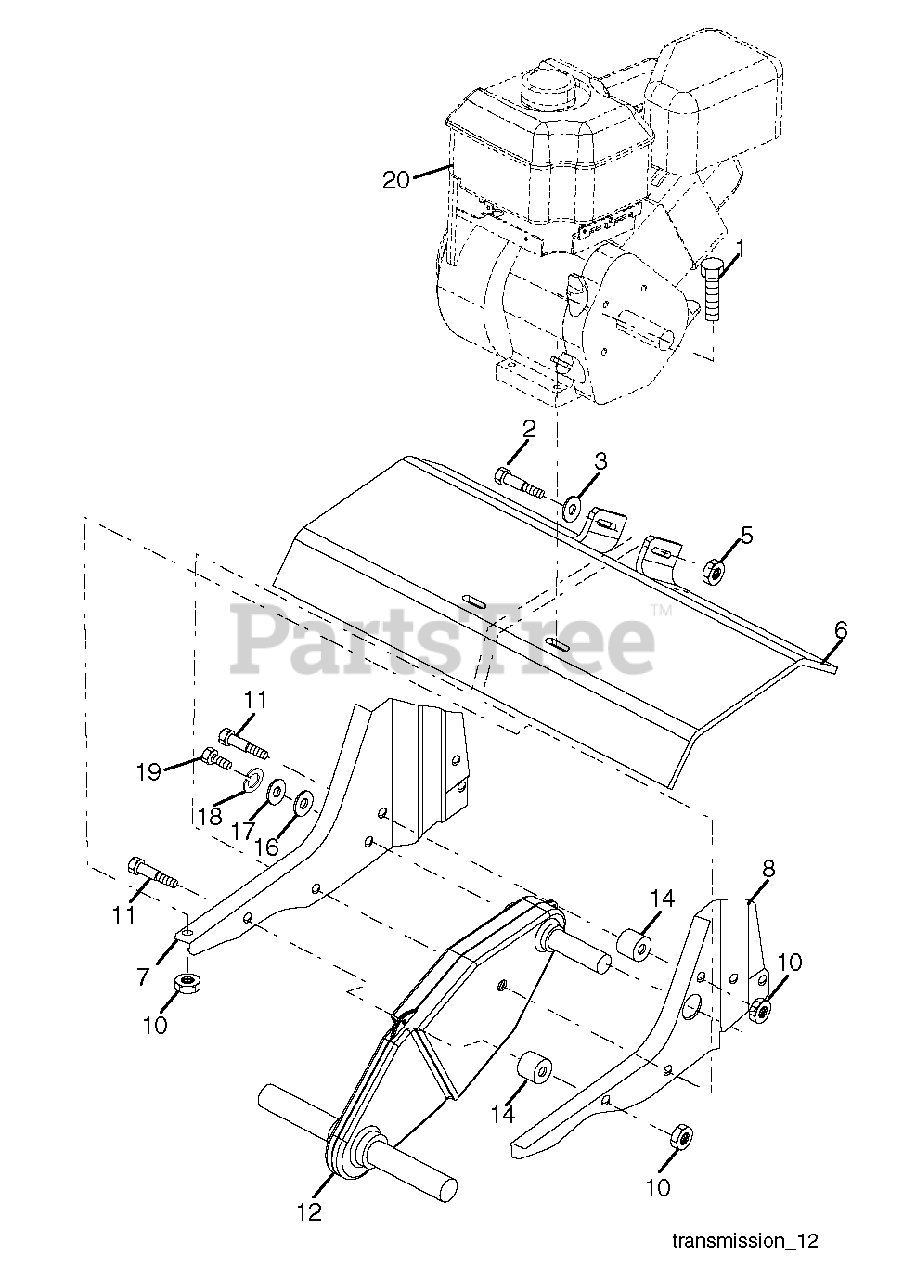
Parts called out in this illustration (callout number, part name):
1	BOLT
5	NUT LOCK FLG 3/8-16 UNC
7	BRACKET.ENGINE.RH.TILLER.BLACK
8	BRACKET.ENGINE.TILLER.BLACK
10	LOCKNUT-FLANGE 5/16-18
11	BOLT, HEX HEAD 5/16-18 X 2.5
12	TRANSMISSION.ASM.W/1".D-SHAFT
14	SPACER.SPLIT.327 X 1.00
18	LOCKWASHER
